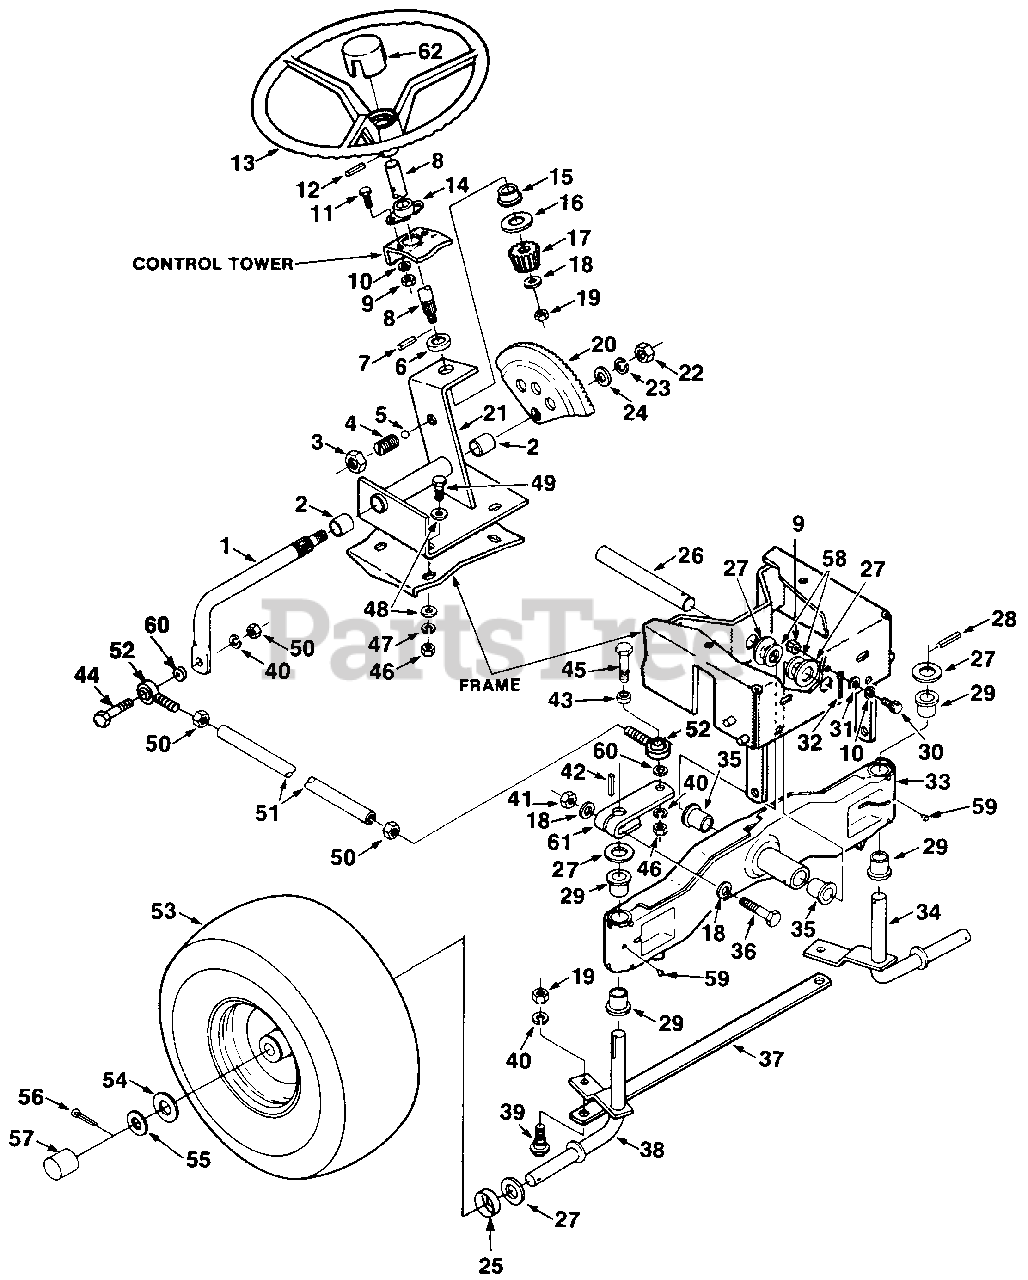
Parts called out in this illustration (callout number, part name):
1	ARM- Pitman
3	NUT- (5/8")
4	SPACER- Bearing
5	BALL- (.312 dia)
6	SPACER- Steering
7	PIN- Roll (3/16 x 1")
8	SHAFT- Steering wheel
9	NUT- Hex (1/4-20)
10	WASHER- Lock (1/4")
11	SCREW- Hex (1/4-20 x 1/2")
12	PIN- Roll (1/4 x 1")
13	WHEEL- Steering
14	BEARING- Steering shaft
17	PINION- Steering
19	NUT- Hex (3/8-16)
20	GEAR- Steering
21	SUPPORT- Steering
22	NUT- Hex (1/2-13)
23	WASHER- Lock (1/2")
24	WASHER- Flat (1/2")
25	WASHER- Dust
27	WASHER- Flat (3/4")
28	PIN- Roll (1/4 x 1 1/2")
29	BUSHING- Spindle
30	SCREW- (1/4-20 x 7/8")
31	WASHER- Plain (1/4")
32	PIN- Cotter
33	FRONT AXLE ASSY
36	SCREW- Hex (3/8-16 x 2 1/4")
38	SPINDLE- R.H.
39	BOLT- Tie bar mounting
40	WASHER- Lock (3/8")
41	NUT- Centerlock (3/8-16)
42	KEY- (3/16 x 1 1/2")
43	SPACER- Ball joint
44	SCREW- (3/8-16 x 1 1/2")
45	SCREW- Hex (3/8 x 16 x 1 3/4")
46	NUT- Hex (5/16-18)
47	WASHER- Lock (5/16")
48	WASHER- (5/16")
49	SCREW- Hex (5/16-18 x 7/8")
50	NUT- Hex (3/8-24)
52	BALL JOINT
53	RIM & TIRE ASSY
55	WASHER-HT
56	PIN- Cotter (5/32 x 1 1/4")
59	FITTING- Grease
60	SPACER- Ball joint
61	ARM- Steering
62	CAP- Steering wheel
